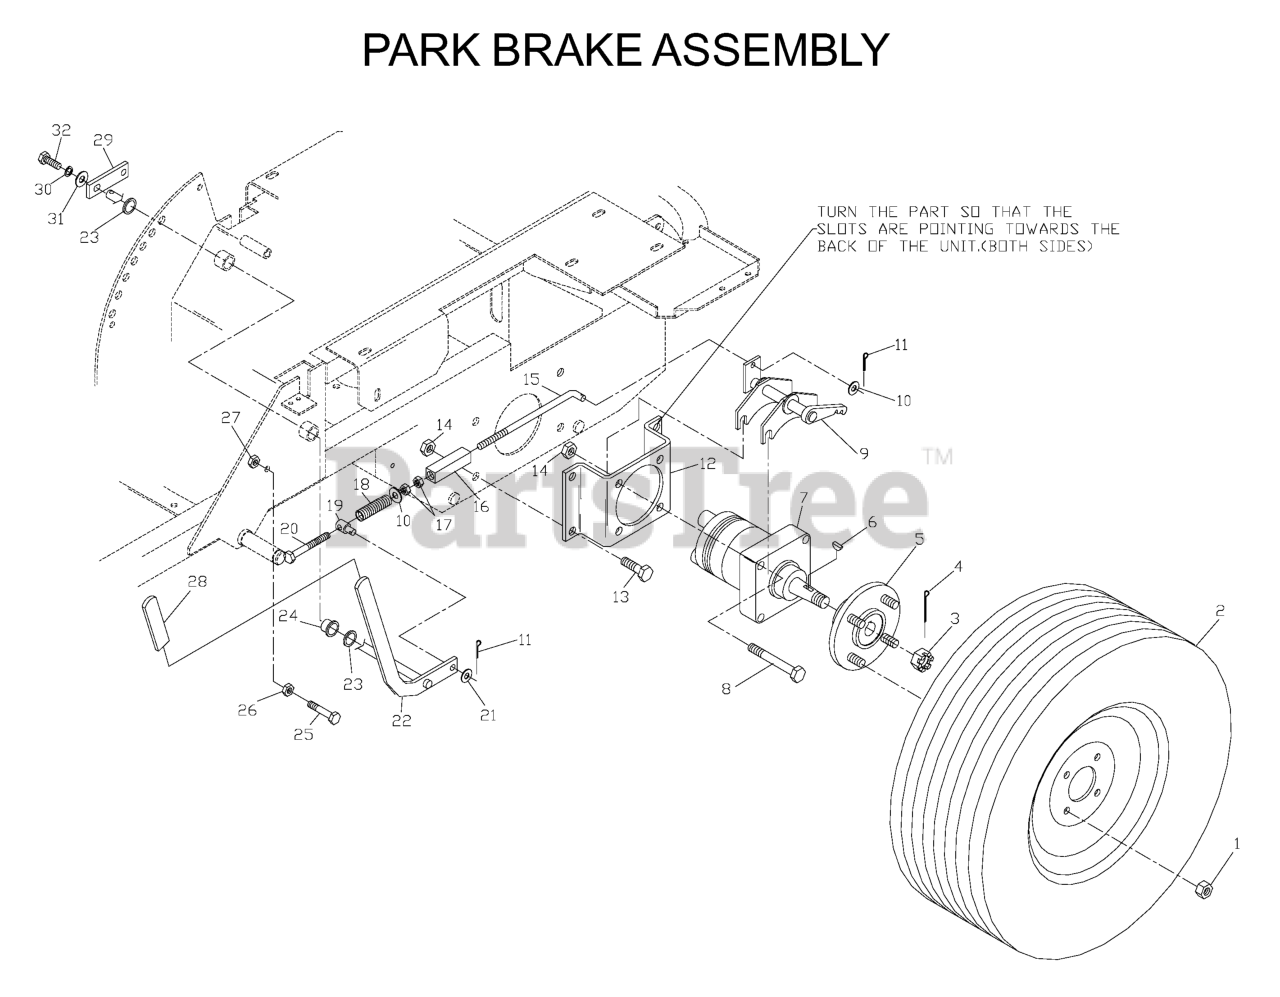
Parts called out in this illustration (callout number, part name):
1	LUG NUT 1/2F
2	TIRE ASM GRAY REAR
3	NUT 3/4-16 HEX SLTD GR5 ZD
4	COTTER PIN
5	HUB W/SPROCKET
6	KEY, #808 WOODRUFF
7	WHEEL MOTOR
8	HCS 1/2C X 2 3/4
9	BRAKE WELDMENT, LEFT
10	WASHER 5/16 FLAT
11	RP_COTTER PIN 1/8 X 3/4
12	MOTOR STANDOFF
13	HCS 1/2C X 1 1/4 SERRATED HEAD
14	NUT 1/2-13 HEX NYLOC ZD
15	BRAKE LINKAGE
16	TURNBUCKLE
17	NUT 5/16C HEX
19	BRAKE SWIVEL
20	HCS 5/16C, SPECIAL
21	WASHER 3/8 FLAT
22	PIVOT SHAFT WELDMENT
23	BUSHING 1/2 MACH
25	HCS 3/8-16 X 1 3/4 GR5
26	NUT 3/8C WHIZ
27	NUT 3/8C CENTERBLOCK
29	ARM, PARK BRAKE
30	LOCKWASHER 1/4"
31	WASHER 1/4 FLAT
32	HCS 1/4C X 5/8
539103265	BRAKE WELDMENT, RIGHT
539104601	RIM GRAY
539912234	VALVE STEM TR-412
